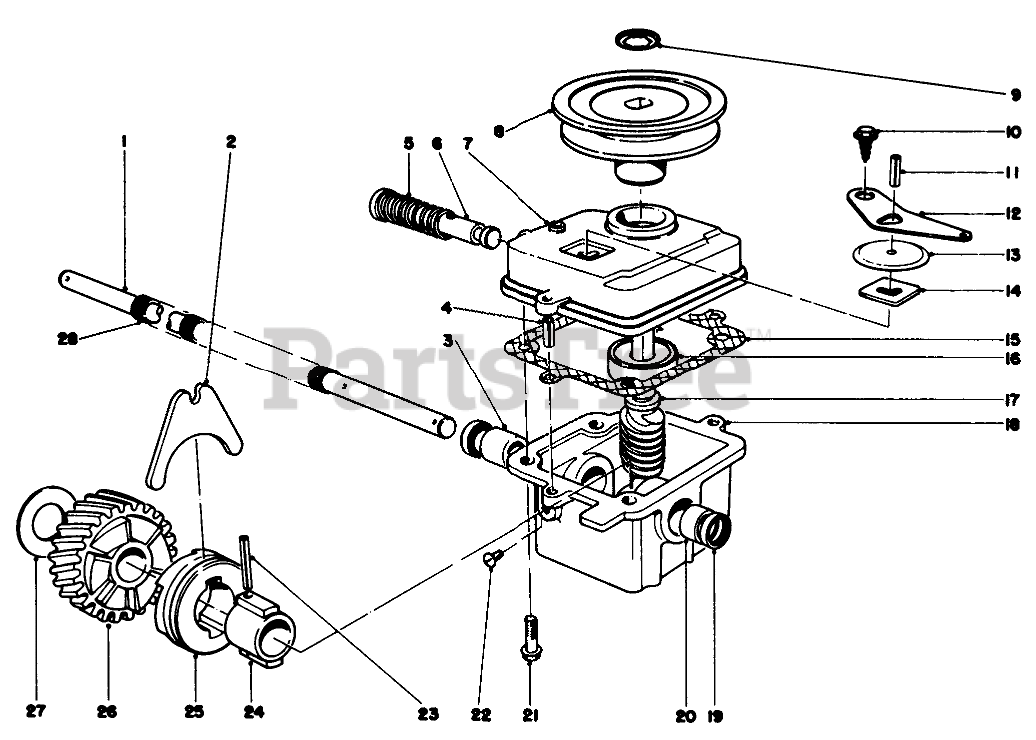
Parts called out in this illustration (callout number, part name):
1	DRIVE SHAFT (SERVCE)
2	SHIFTER FORK
3	Bushing
4	3/16 X 1/2 ROLL PIN
5	SPRING
6	Shift Rod
7	Cover Gear Case
8	PULLEY
9	PUSH-ON 93-3236
10	Screw
11	PIN-ROLL
12	SHIFTER ARM
13	TRANS DUST COVER
14	LATCH PLATE
15	GASKET
16	Bearing
17	Worm Shaft (Incl. Ref. #26)
18	Gear Case (Incl. Ref. #3, 19-20)
19	Seal
20	Bushing
21	Screw
22	NYLON SCREW
23	Pin
24	SLEEVE
25	CLUTCH JAW
26	Helical Gear
27	THRUST WASHER
28	DRIVE SHAFT COVER
